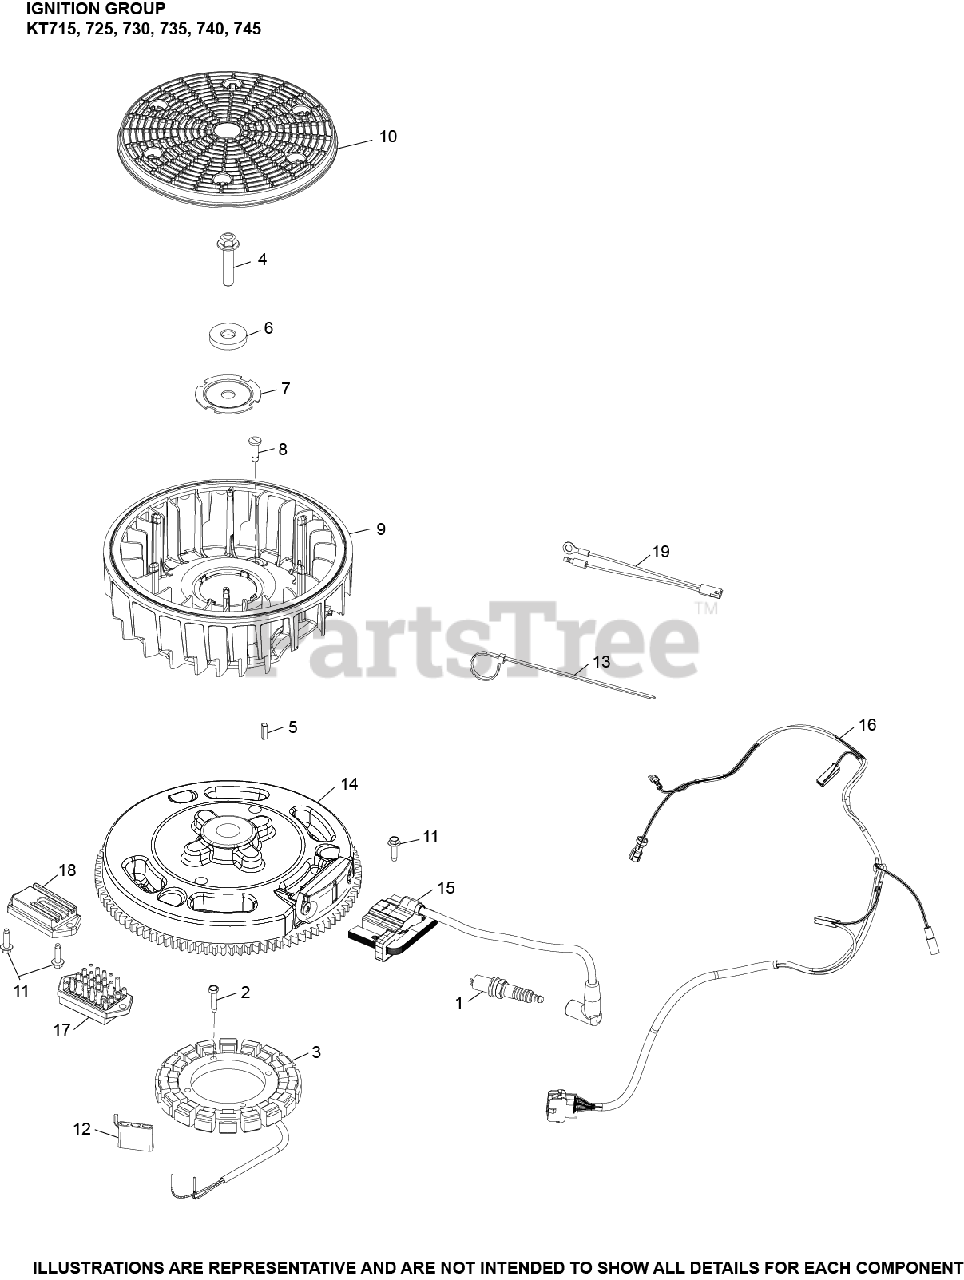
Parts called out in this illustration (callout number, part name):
1	PLUG, SPARK (STD)
2	SCREW, THREAD FORMING
3	KIT, 15 / 20 AMP STATOR
4	SCREW, HEX FLANGE
5	KEY, SQUARE
6	WASHER, FLAT
7	PLATE, FAN MOUNTING
8	RETAINER, FLYWHEEL FAN
10	SCREEN, GRASS
11	SCREW, THREAD FORMING - USE 25 086 473-S
12	CONNECTOR
13	TIE, WIRE
14	FLYWHEEL ASSEMBLY
15	MODULE, MAGNETO DIGITAL IGNITION USE 32 584 09-S
16	HARNESS, WIRING ASSEMBLY USE 32 176 52-S
18	REGULATOR/RECTIFIER
19	LEAD, JUMPER
